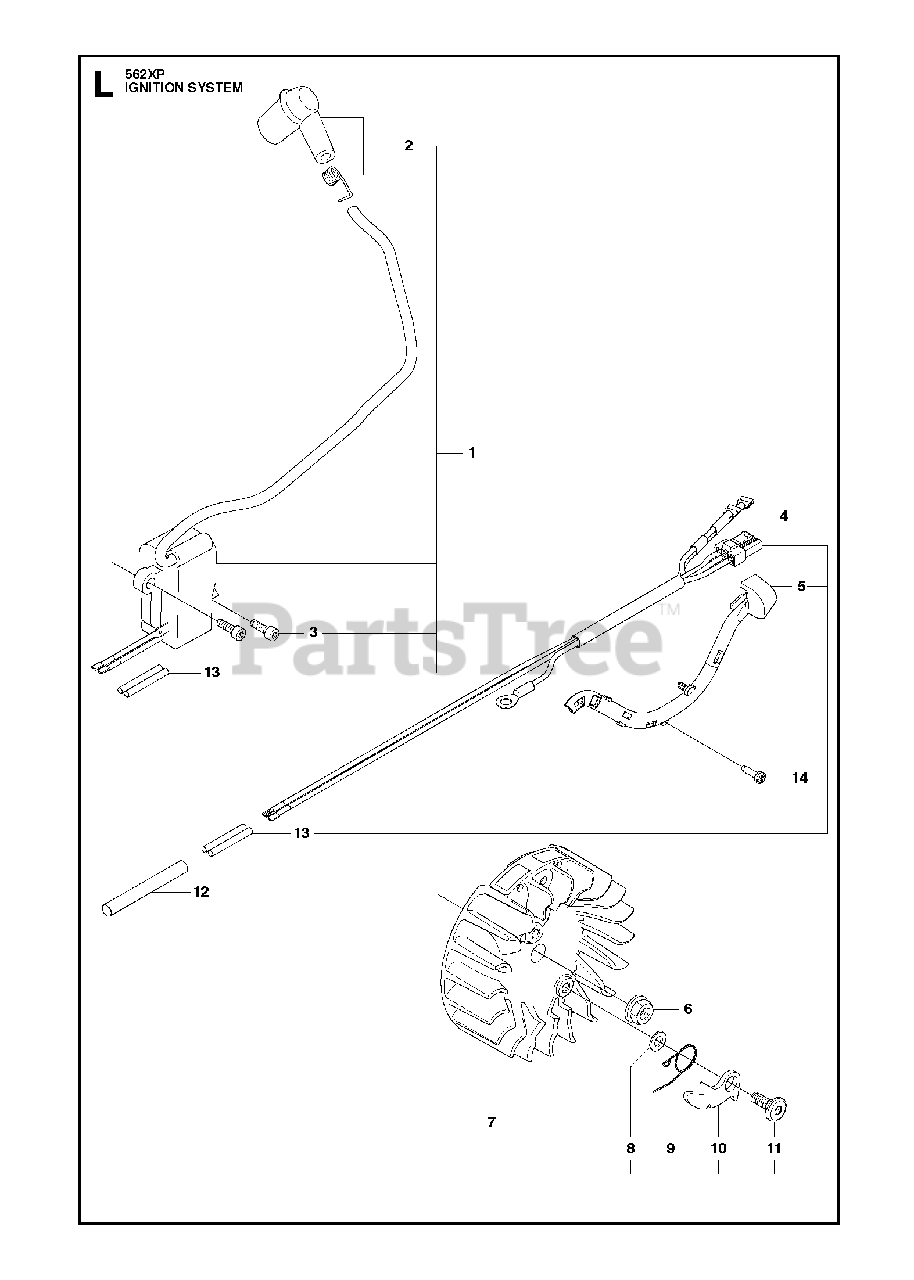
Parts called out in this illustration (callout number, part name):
1	IGNITION MODULE ASSY
2	SPARK PLUG CAP ASSY
3	SCREW
4	WIRING ASSY
5	CABLE HOLDER
6	NUT W/ WASHER
7	FLYWHEEL ASSY
11	SCREW M5X14
12	CABLE COVER
13	SHRINK HOSE
14	SCREW
